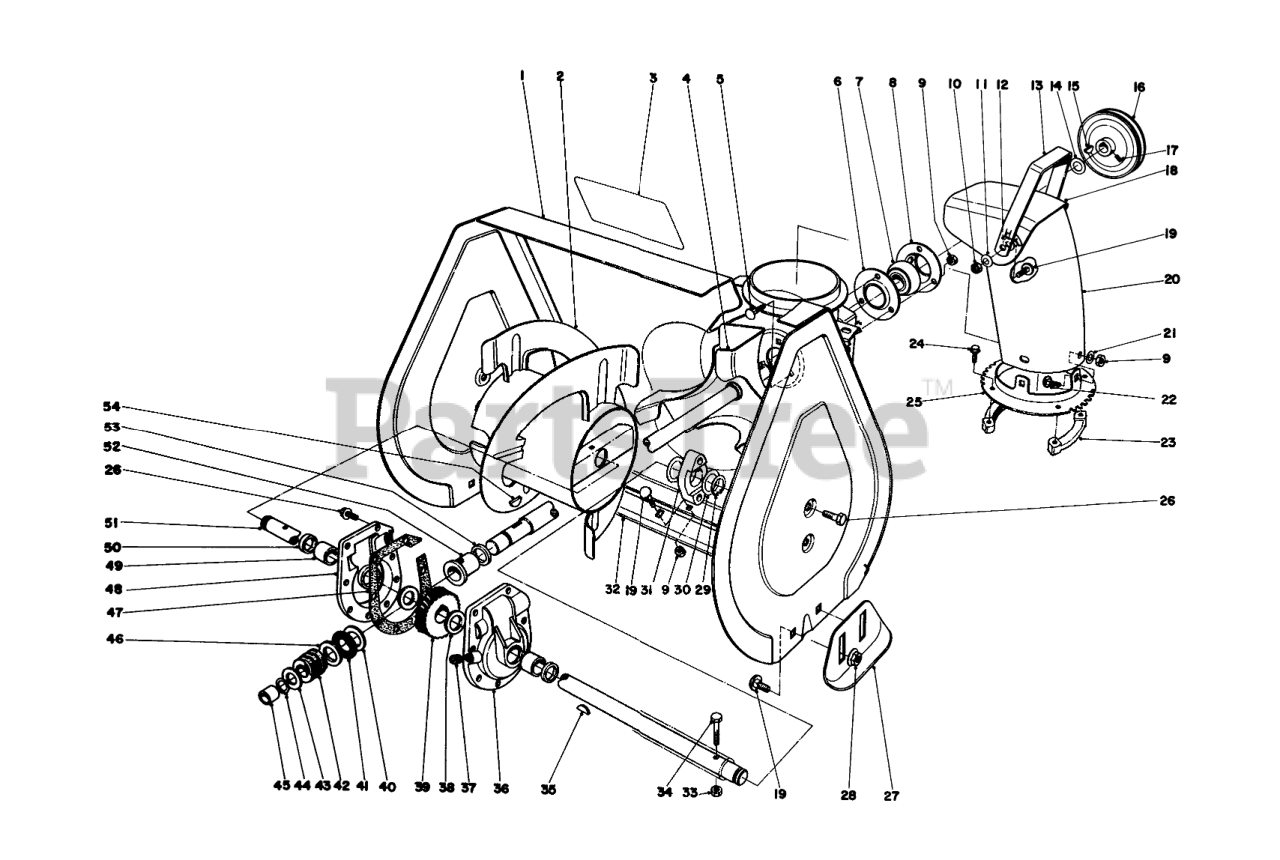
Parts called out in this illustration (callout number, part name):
1	Auger Housing
2	Auger L.H.
3	Decal-Warning
4	Shaft & Impeiler
5	BOLT-CARR
6	FLANGE-CUP, BEARING
7	Ball Bearing
8	FLANGE-CUP, BEARING
9	NUT-LOCK, NI
10	NUT-LOCK, CONE
11	WASHER-BELLEVILLE
12	WASHER-RUBBER
13	Handle Deflector
14	WASHER
15	KEY-WOODRUFF
16	PULLEY
17	SCREW-SET, SQH
18	Deflector
19	BOLT-CARR
20	Chute-Discharge
21	WASHER-PLAIN
22	SCREW-CARR
23	RING-CHUTE, RETAINER
24	SCREW-SPECIAL
25	Chute Ring
26	SCREW-HWHTF
27	Skid
28	NUT-HF
29	RING-RETAINING
30	WASHER
31	BEARING-AUGER
32	Blade-Scraper
33	NUT-LOCK, CONE
34	SCREW-HH
35	KEY-WOODRUFF
36	Gear Case R.H. (Incl. Ref. #49 & 50)
37	PLUG-PIPE, SQH
38	WASHER-THRUST
39	Gear
40	WASHER-THRUST
41	BEARING-THRUST
43	WASHER-THRUST
44	Ring-Snap
45	BUSHING
46	WASHER-THRUST
47	Gasket
48	Gear Case L.H. (Incl. Ref. #49 & 50)
49	BUSHING
50	SEAL-OIL
51	AUGER SHAFT
52	BUSHING-INPUT
53	RING-QUAD
54	KEY-WOODRUFF
